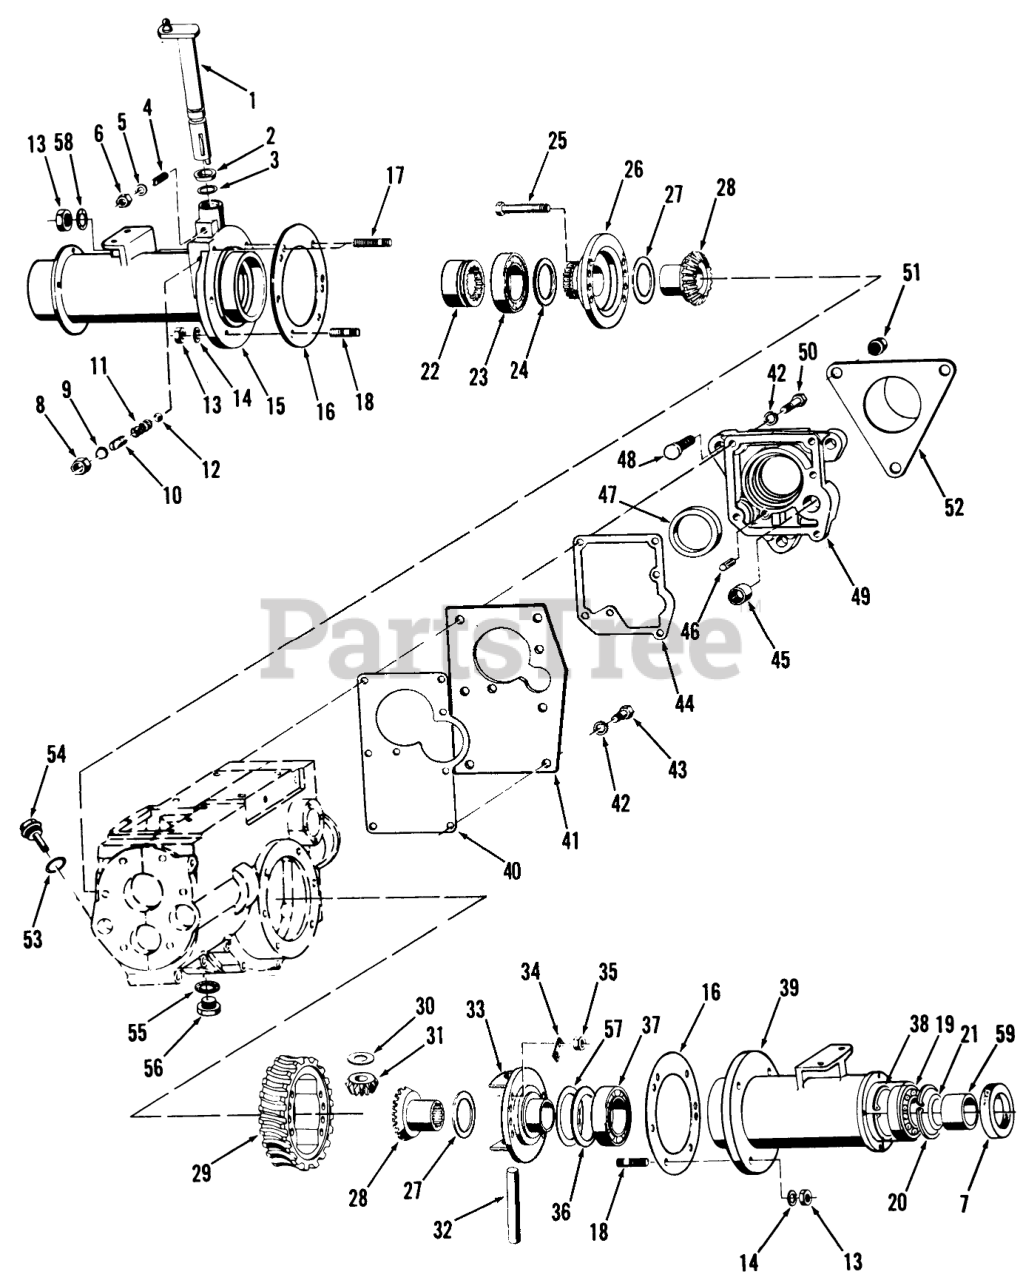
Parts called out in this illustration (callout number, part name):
1	Shifting Shaft
2	Seal
3	Round Cord Ring
4	Stud
5	Seal
6	Nut
7	Oil Seal
8	Nut
9	Seal
10	Stud
11	Spring
12	Ball
13	Nut
14	Washer
15	Flared Tube of Rear Right Axle
16	GASKET-REAR AXLE TUB
17	Stud
18	Stud
19	Ball Bearing
20	Retaining Ring
21	O-Ring
22	Shifting Socket
23	Ball Bearing
24	Shim (68 X 55.2 X 0.2)
24	Shim (68 X 55.2 X 0.3)
25	Screw
26	Dierential Cover
27	Shim (66 X 42.1 X 0.2)
27	Shim (66 X 4 .1 X 0.3)
28	Differ. Pinion Grand (Only Deliverable Part 31)
29	Worm Gear
30	Shim (38 X 18.1 X 0.2)
30	Shim (38 X 18.1 X 0.3)
31	Differ. Pinion Little (Only Deliverable Part 28)
32	Differential Shaft
33	Differential Carrier
34	Lock Plate
35	Nut
36	Shim (62 X 50.5 X 0.2)
36	Shim (62 X 50.5 X 0.3)
37	Ball Bearing
38	Retaining Ring
39	Flared Tube of Rear Axle
40	GASKET-REAR PTO
41	Support
42	Washer
43	Screw
44	GASKET-REAR PTO
45	Needle Bushing
46	Pin
47	SEAL RING-REAR PTO
48	Screw
49	Cover
50	Bolt
51	Nut
52	Rear P.T.O. Cover
53	Seal Ring
54	Dipstick
55	Gasket
56	Plug
57	Shim (50 X 62 X 0.5 DIN 988)
57	Shim (50 X 62 X 1 DIN 988)
58	Lock Washer
59	Bushing
